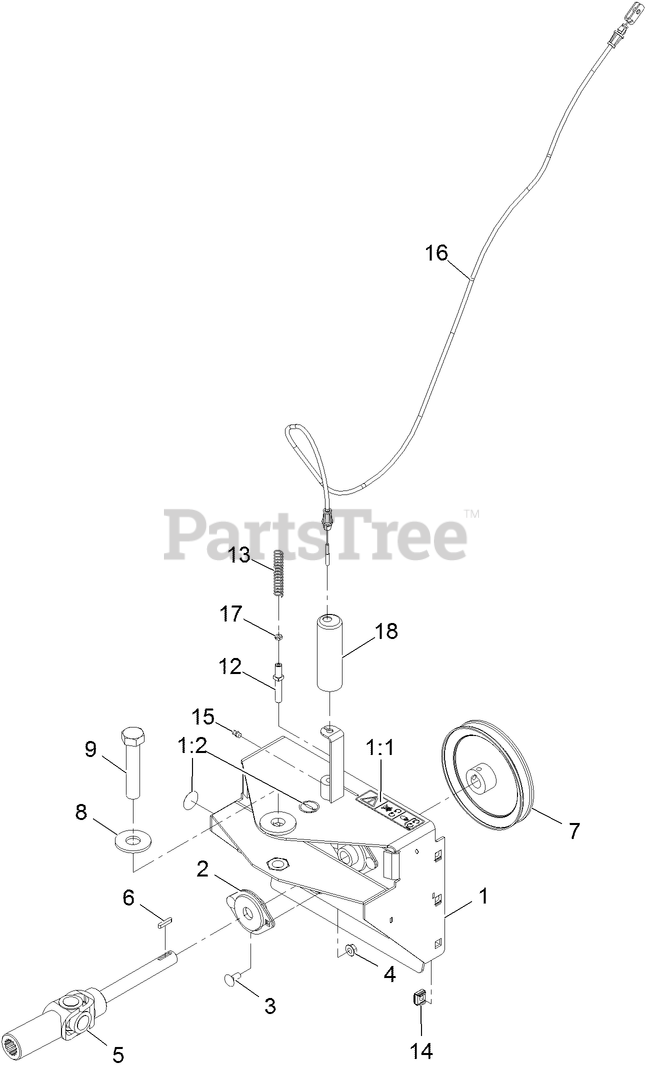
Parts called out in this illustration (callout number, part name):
1	BROOM MOUNTING FRAME ASM
1:1	DECAL-MISSING, COVER
1:2	DECAL-GREASE
2	BEARING-SHAFT
3	BOLT-CARR
4	NUT-HF
5	SHAFT-DRIVE
6	KEY-ROUND END
7	PULLEY-IMPELLER
8	WASHER-FLAT
9	SCREW-HH
12	PIN-SWING
13	SPRING-COMPRESSION
14	NUT-RETAINER
15	FITTING-GREASE
16	CABLE-ANGLE, BROOM
17	NUT-HEX
